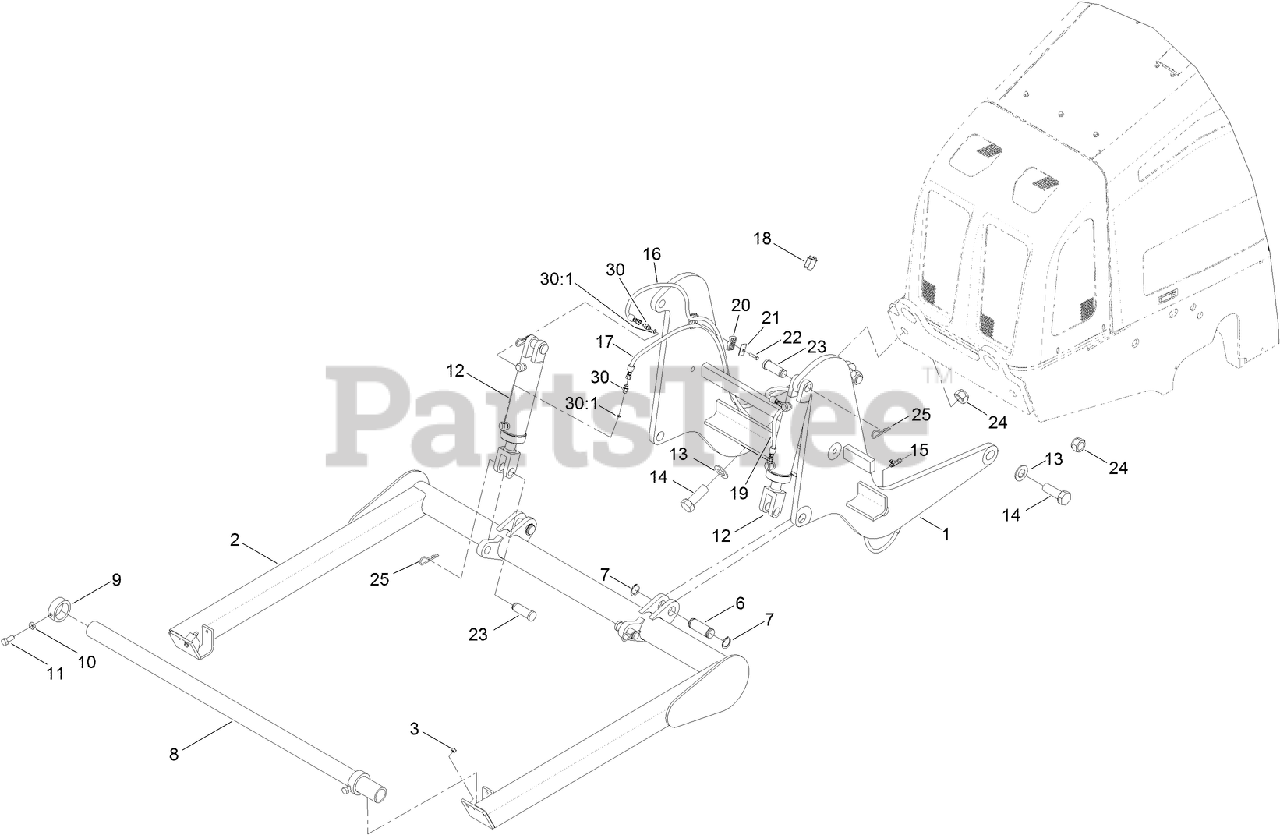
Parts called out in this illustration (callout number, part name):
1	FRAME-COUNTERWEIGHT
2	ARM-REEL CARRIER
3	NUT-HEX
7	RING-RETAINING, EXTERNAL
9	COLLAR-REEL
10	NUT-JAM
11	SCREW-HH
12	HYD CYLINDER ASM
15	FITTING-HYD, TEE
16	HYD HOSE ASM, HP
17	HYD HOSE ASM, HP
18	SWITCH-ROCKER, 2 POLE
19	HYD HOSE ASM
20	CLAMP-TUBE
21	COVERPLATE
22	SCREW-HH
23	PIN-CLEVIS
25	PIN-COTTER, QUICK ATTACH
30	FITTING-STRAIGHT
30:1	O-RING
